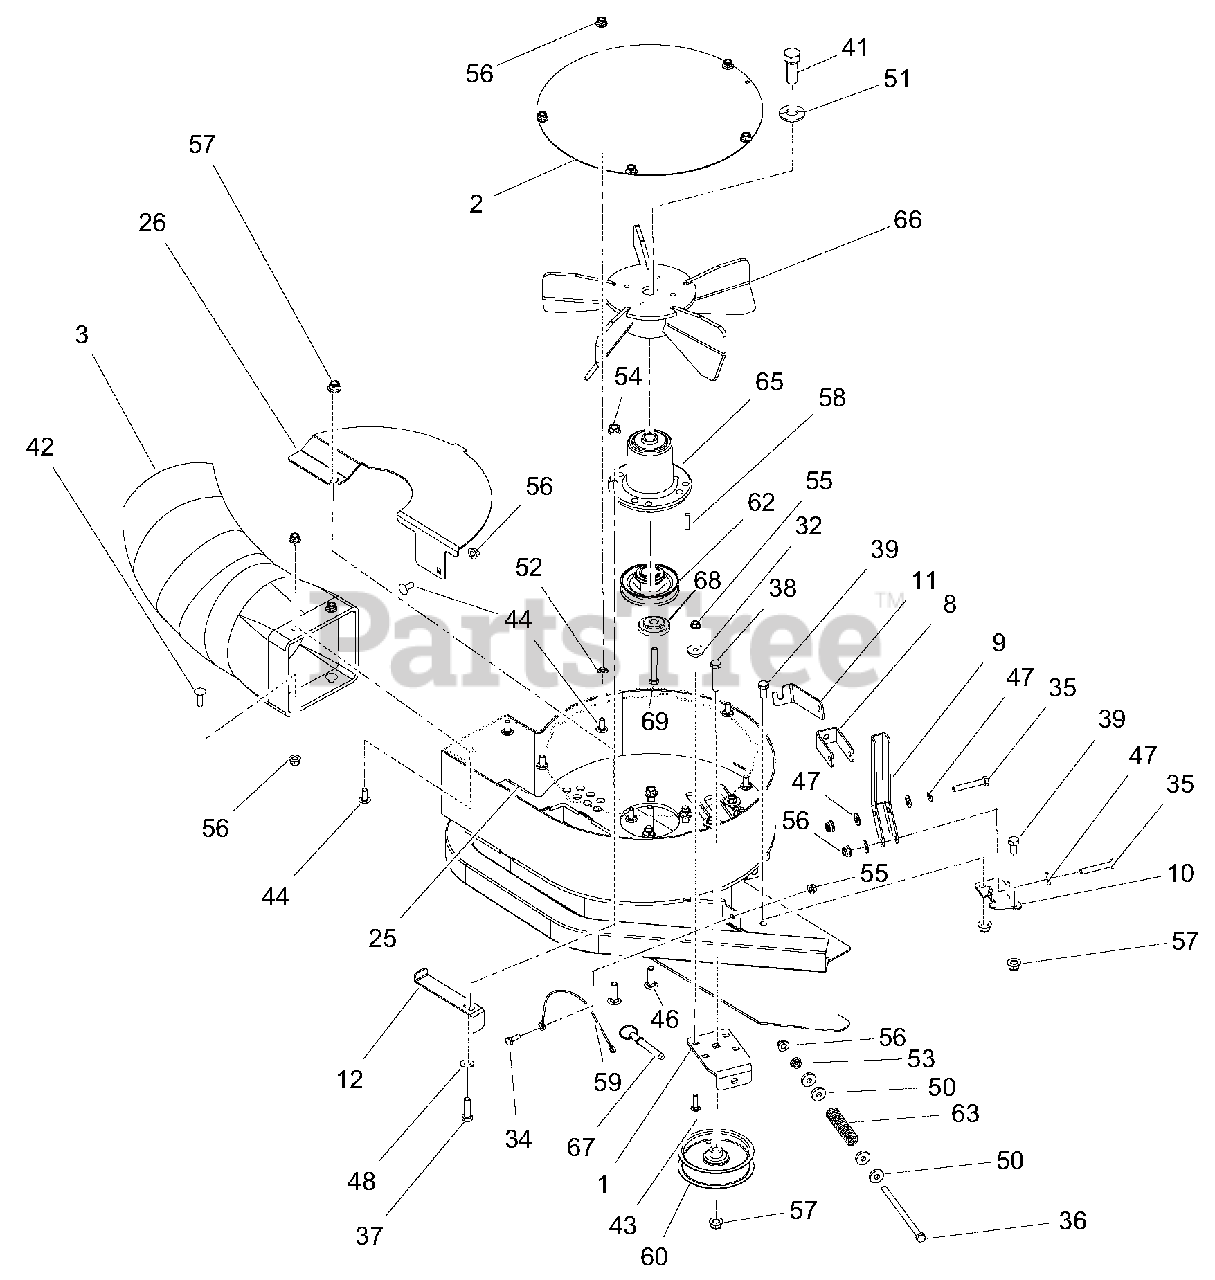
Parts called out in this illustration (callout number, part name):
1	BRKT, ADJUSTABLE IDLER
2	COVER, BLOWER -BLACK
3	ADAPTER, HOSE
8	LINK, IDLER RELEASE-BLACK
9	LEVER, IDLER RELEASE-BLACK
10	MOUNT, IDLER RELEASE LEVER-BLK
11	LOCK, IDLER RELEASE LEVER-BLACK
12	FINGER BELT-BLACK
25	WELDMENT, BAGGER BLOWER-RED
26	COVER, BOTTOM - BLK
32	BSHG, FLG .265 X .477 X .375 X 1.00
34	BLT-HEX .25-20 X .75
35	BLT-HEX .31-18 X 2.00
36	BLT-HEX .31-18 X 5.50
37	BLT-HEX .38-16 X 1.25
38	BLT-HEX .38-16 X 1.75
39	@BLT-HEX .38-16X.75 GR5 YWZC
41	BLT, HEX .62-18 X 1.75
42	BLT-RDHDSQSHNK .31-18 X 1.00
43	BLT-RDHDSQNK .25-20 X 1.00
44	BLT-RHDSSQNK .31-18 X .75
46	BLT-RDHDSQNK .38-16 X 1.25
47	WSHR-FL-NYL .375 X .75 X .060
48	WSHR-FL-STL.406 X .812 X .065
50	WSHR-FL-STL .328 X .87 X .179
51	WSHR, BLVL .63 X 1.625 X .14
52	NUT, PUSH .312
53	NUT-SPNLK-FLG .312-18
54	NUT, LK-CTR-FLG .38-16
55	NUT, LK-TOP-FLG .25-20
56	NUT-LK-NYL-FLG .31-18
57	NUT-LK-NYL-FLG .38-16
58	KEY SQUARE .25 X .25 X 1.00 RC 40 - 50
59	LANYARD, 12"
60	PULLEY, IDLER 4.00 X .375
62	PULLEY, 1" OD X 3.50" OD-LOW FILM
63	SPRG, COMPRESSION
65	SPINDLE BLOWER ASSEMBLY
66	WLDMT, IMPELLER FAN
67	PIN, SPRING BALL .375 OD X 1.50
68	RETAINER, SHEAVE
69	BLT-HEX .38-16 X 2.75
